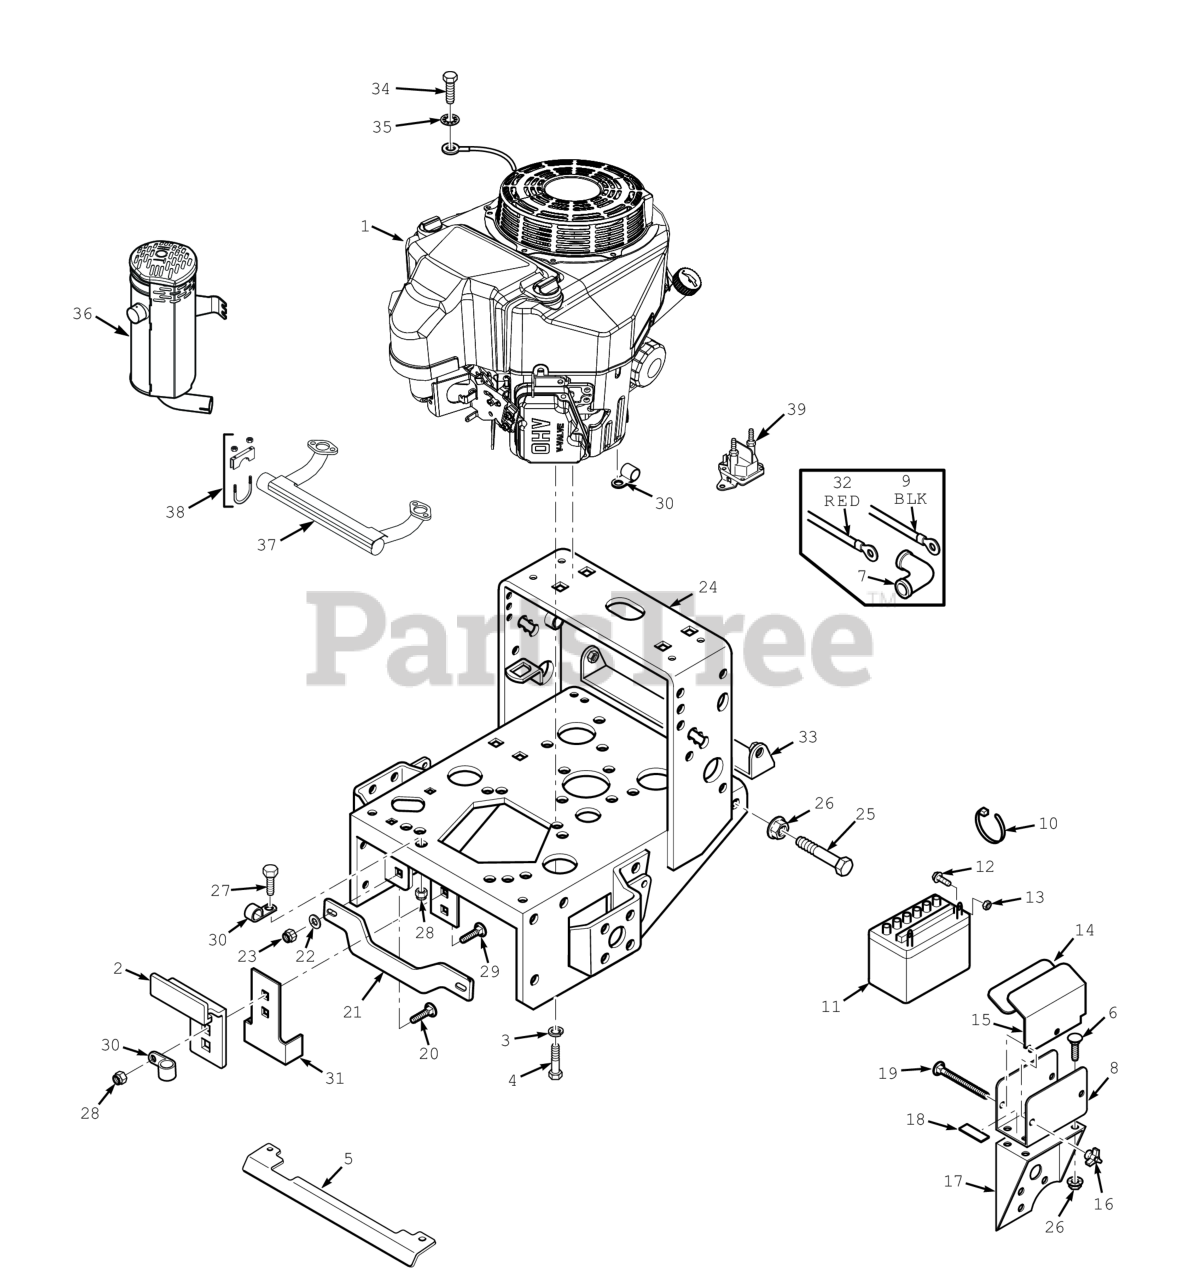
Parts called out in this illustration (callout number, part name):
2	Plate, Clutch Bracket
3	Lockwasher, 3/8" Spring, Kawasaki FX / FT & FT-EFI / B&S 32BV
4	Bolt, Hex Head 3/8-16 x 1-1/4", Kawasaki FX / FT & FT-EFI
5	Heatshield, 16" Small Frame
6	Bolt, 5/16-18 x .75 RHSN Carriage
7	RUBBER BOOT
8	Plate, Battery Box
9	Battery Cable, 31-1/2" Black (25KA, 26DFI, 31DFI) - Kawasaki
10	Cable Tie, .19 x 8.0"
11	Battery (Not Available Through Scag)
12	Bolt, Hex Head 1/4-20 x .5" Battery, (Not Available Through Scag)
13	Nut, 1/4 - 20 Hex
14	INSULATION, BATTERY COVER
15	Battery Box Cover
16	ELASTIC STOP WINGNUT, 1/4-20
17	Battery Support
18	PAD, BATTERY SUPPORT
19	Bolt, Carriage 1/4-20 x 6"
20	SHORT SQ. NECK CARRIAGE BOLT, 3/8-16 X 1-1/4"
21	Brace, (16" Small Frame)
22	Flatwasher, 3/8 (.391 x .938 x .105 HD) Grade 8
23	HEX NUT, ELASTIC STOP LOCK, 3/8-16
24	Engine Deck (16" Wide) with Decals - Small Frame
25	Bolt, Hex Head 5/16-18 x 2-1/2" (x3) (35BV & 37BV-EFI)
26	Nut, Serrated Flange 5/16-18 (Right Front Engine Mounting, Briggs and Kohler Only)
27	BOLT, SERRATED FLANGE HEX HEAD 5/16-18 X 3/4"
28	HEX NUT, ELASTIC STOP LOCK, 5/16-18
29	Bolt, Carriage 5/16-18x1" (large frame units only)
30	Clamp, Cable 1/2" I.D.
31	Plate, Clutch Anti-Rotation
32	Battery Cable, 25" Red (Kawasaki)
33	Pulley Guard, 16" Small Frame
34	Bolt, Hex Head M8 - 1.25 x 16 (48V / 52V)
35	Lockwasher, 5/16" Ext. Tooth (Kohler x1)
36	Muffler, Kawasaki (FS481, FS541, FS600)
37	MANIFOLD, 18 FS ENGINE
38	Muffler Clamp
39	Solenoid, Sealed (Briggs & Stratton)
